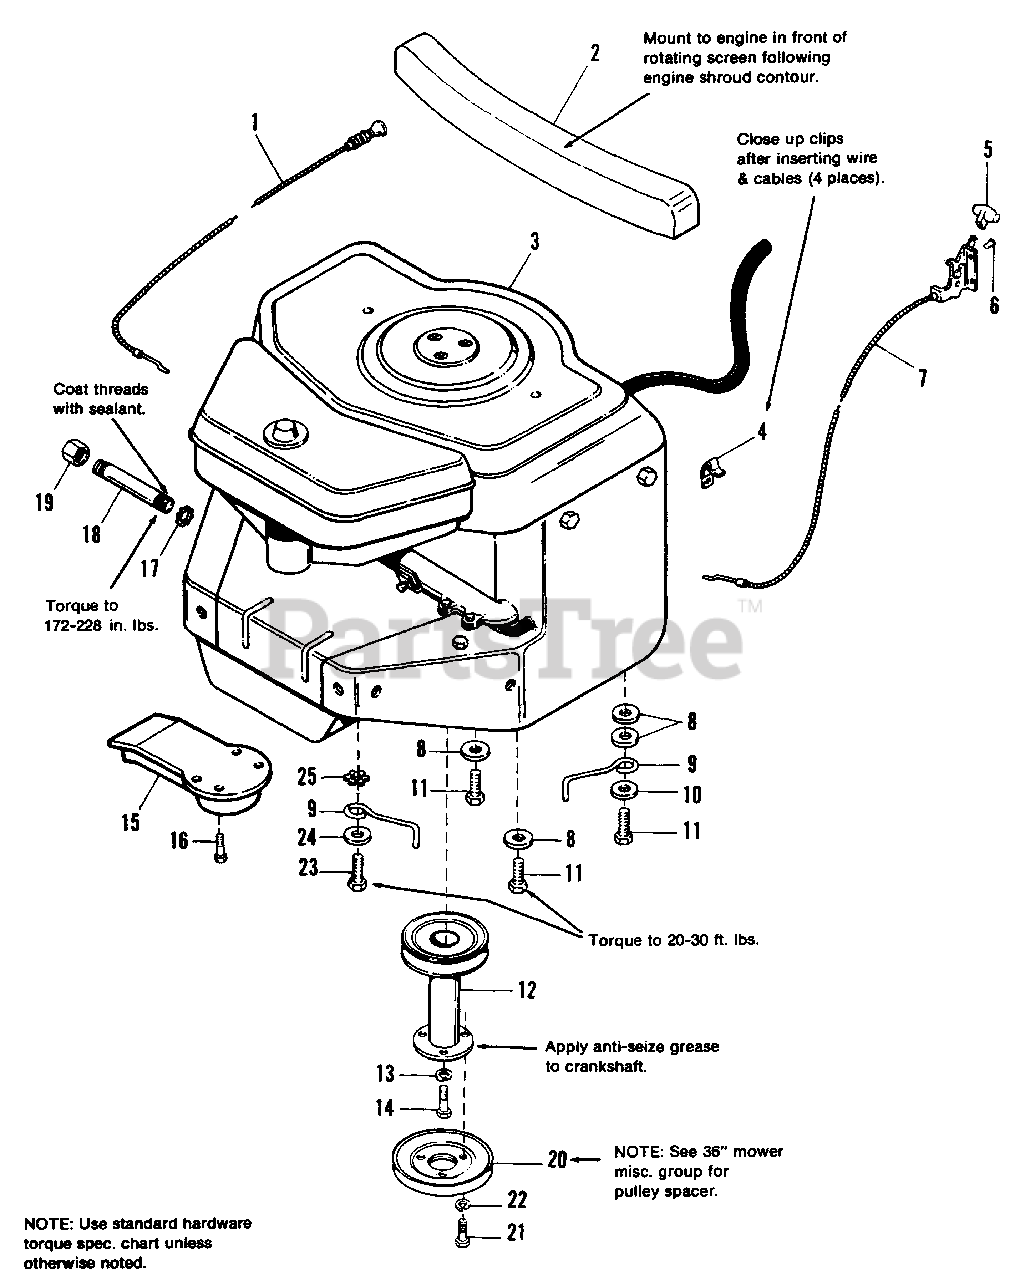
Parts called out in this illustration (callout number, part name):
1	CONTROL, Choke
2	BAFFLE, Engine, Rear
3	ENGINE, 16 H.P.
3	ENGINE, 12.5 H.P.
4	CLIP, Wire
5	KNOB, Throttle
6	RIVET, Pop, 1/4
7	CONTROL ASSY.
8	WASHER, Plain
9	STOP, Belt
10	WASHER, Plain, 3/8
11	SCREW, Taptite, 3/8-16 x 1-1/2
12	PULLEY ASSY., Engine
13	LOCKWASHER, 7/16
14	CAPSCREW, Hex, 7/16-20 x 1-1/4
15	EXTENSION ASSY., Muffler
16	SCREW, Hex Thd., Cutting, #8-32 x 3/8
17	LOCKNUT, Conduit
18	PIPE, Oil Drain
19	PIPE, Cap, Hex
21	CAPSCREW, Hex, 5/16-18 x 1-1/2
22	LOCKWASHER, 5/16
23	SCREW, Taptite, 3/8-16 x 1-1/2 Zinc Plt.
24	WASHER, Zinc Plt.
25	LOCKWASHER, Ext. Tooth, Zinc Plt.
